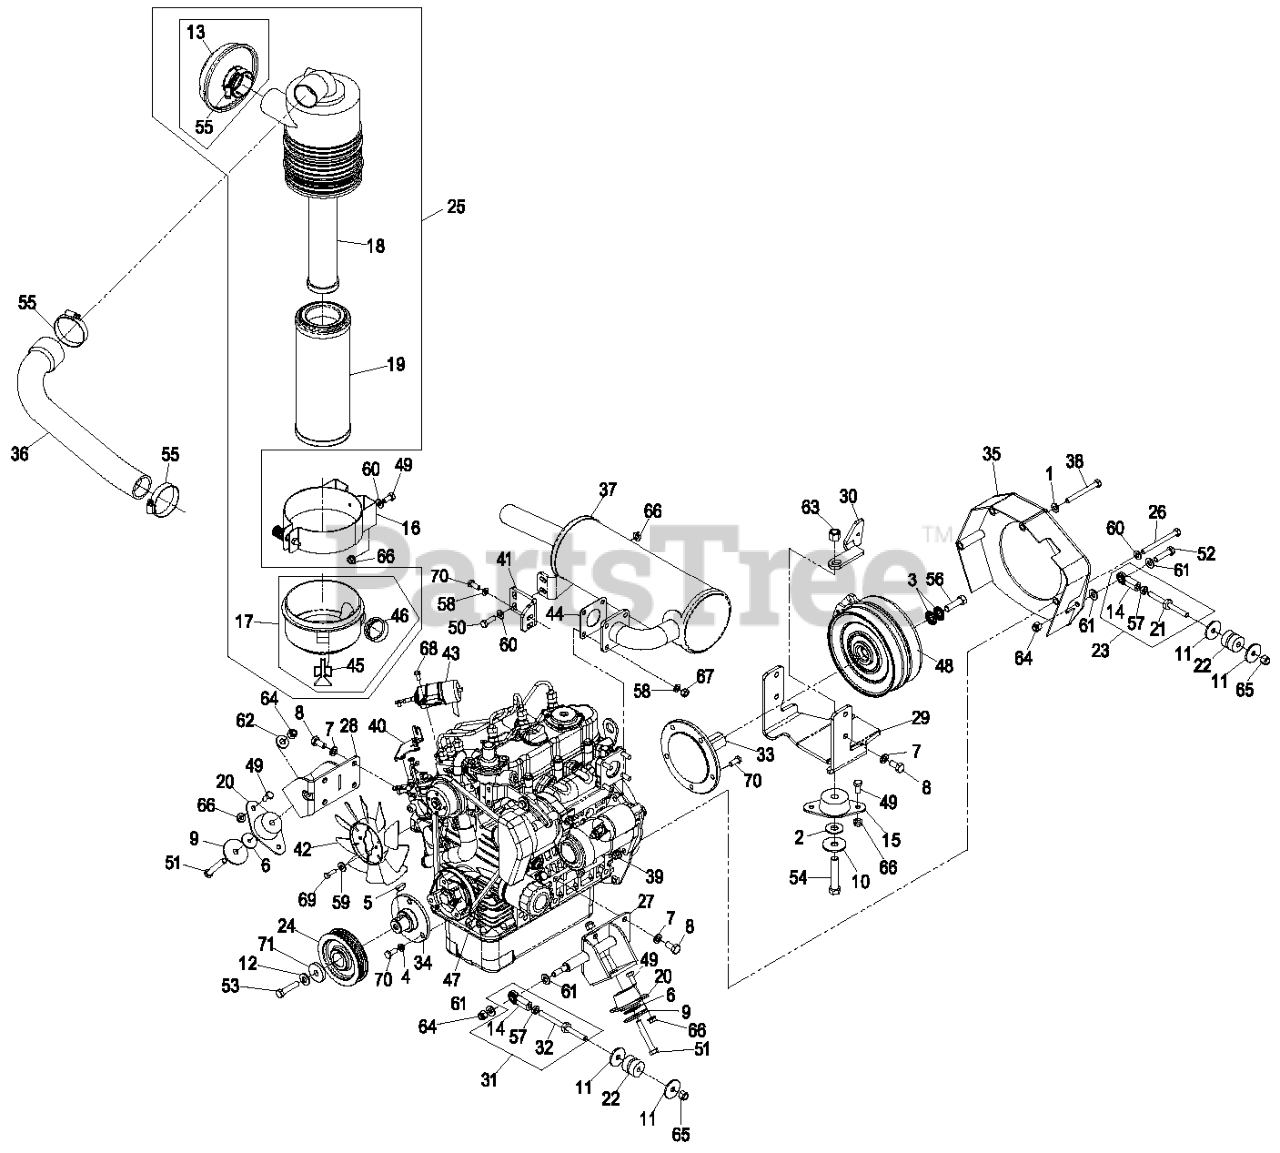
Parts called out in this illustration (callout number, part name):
1	WASHER-SPRING
2	WASHER,FLAT
3	WASHER-SPRING
4	WASHER-LOCK
5	KEY-WOODRUFF
7	Washer, Lock M10
8	SCREW-CAP
9	WASHER-FLAT
10	WASHER-THRUST
12	WASHER-BELLEVILLE
13	HOOD-CLEANER, 2" AIR INTA
14	JOINT-BALL, END
15	ISOLATOR-REAR
16	BRACKET-FILTER, AIR
17	COVER-FILTER, AIR
18	FILTER-AIR, SAFETY
19	FILTER-AIR
20	ISOLATOR-SIDE
21	LINK,REAR A-T AXIAL
22	ISOLATOR-LINK
23	BALL JOINT LINK ASM
24	SHEAVE,5K 4"PD POLY-V
25	FILTER-AIR
26	SCREW-HH
27	WLD,LH ENGINE MOUNT
28	WLD,RH ENGINE MOUNT
29	BRACKET,ENGINE MOUNT
30	ANCHOR,CLUTCH
31	ASM, A-T LINK
32	LINK,REAR A-T AXIAL
33	SHAFT,KUBOTA 902 STUB
34	HUB,PUMP DRIVE
35	WLD,FLYWHEEL COVER
36	HOSE,AIR INTAKE D902(8015
37	ASM,KUBOTA MUFFLER
38	SCREW-HH
39	NUT-LOCK, HHF
40	BRACKET-SUPPORT, THROTTLE
42	FAN,COOLING 7"
43	SOLENOID,FUEL
45	CLIP-CLEANER, AIR
46	EJECTOR, NELSON AIR CLEAN
47	BELT,KUBOTA 902 ALT
49	SCREW-HH
50	SCREW-HH
51	BOLT-CARR
52	SCREW-HH
53	SCREW-HH
54	SCREW-HH
55	CLAMP-HOSE
56	SCREW-HH
57	NUT-HJ
58	WASHER-LOCK
59	WASHER-FLAT
60	WASHER-PLAIN
61	WASHER-FLAT
62	WASHER-FLAT
63	NUT-LOCK, NI
64	NUT-LOCK, NI
65	NUT-LOCK
67	NUT-HEX
68	SCREW-HH
69	SCREW-HH
70	SCREW-HH
71	WASHER-CLUTCH
